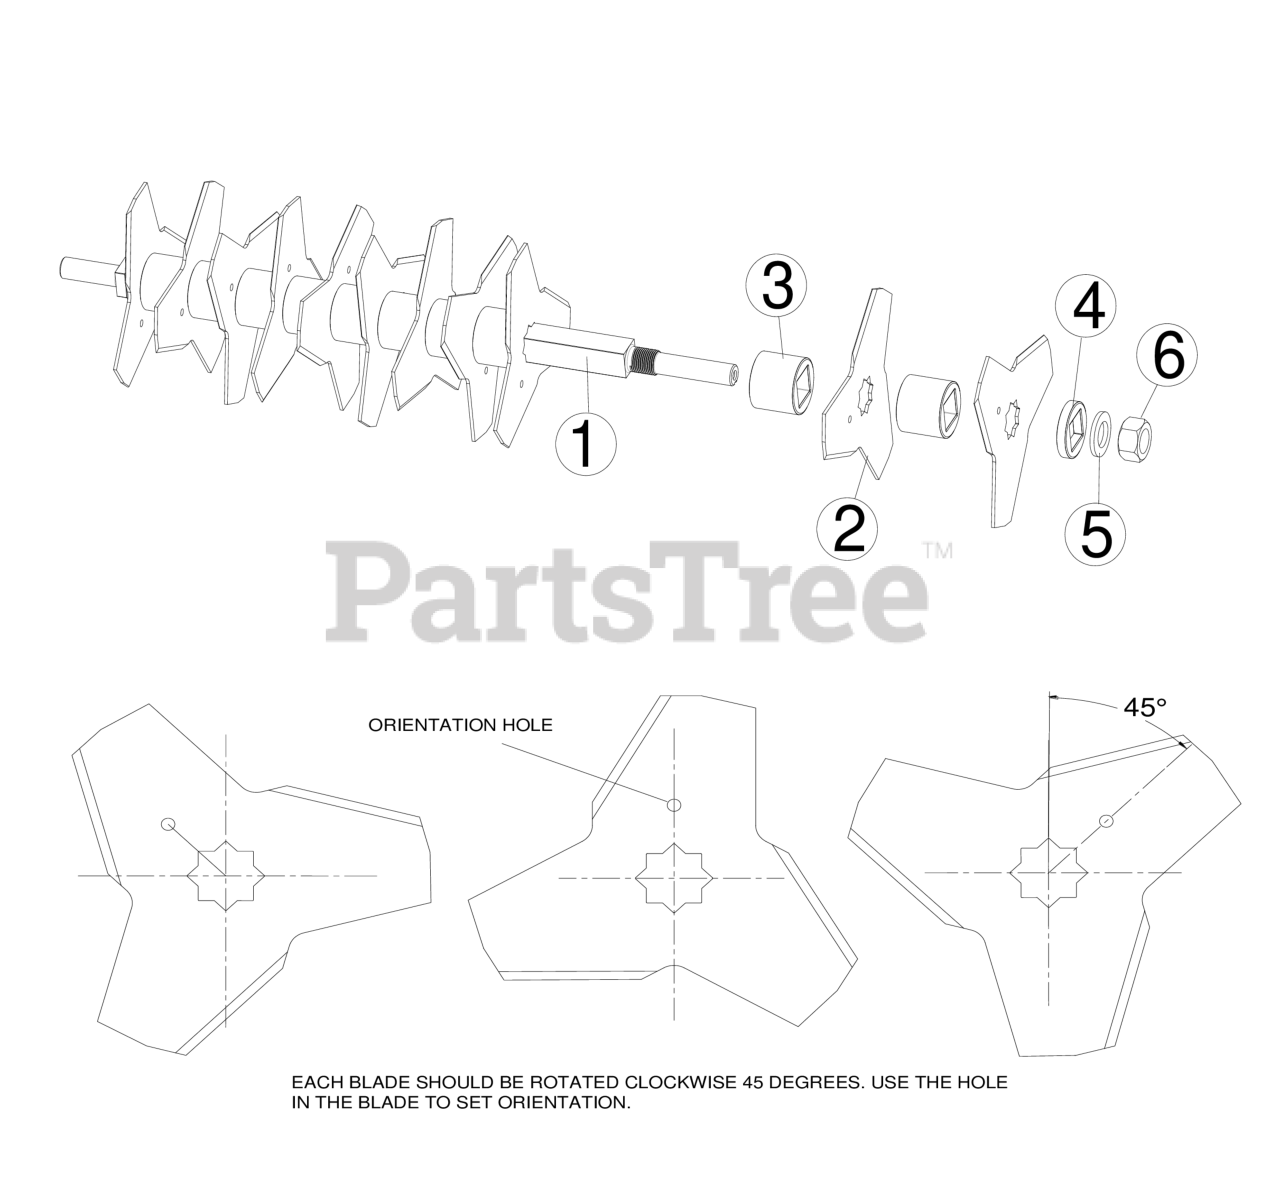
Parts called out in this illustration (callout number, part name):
1	SHAFT VERTICUTTING REEL OSSP
2	BLADE, VERTICUT LASER CLAD
3	SPACER, PM REEL OS900SP
4	SPACER HARDENED REEL
5	SPRING DISC 7/8" ID
6	NUT 7/8-14 NC
